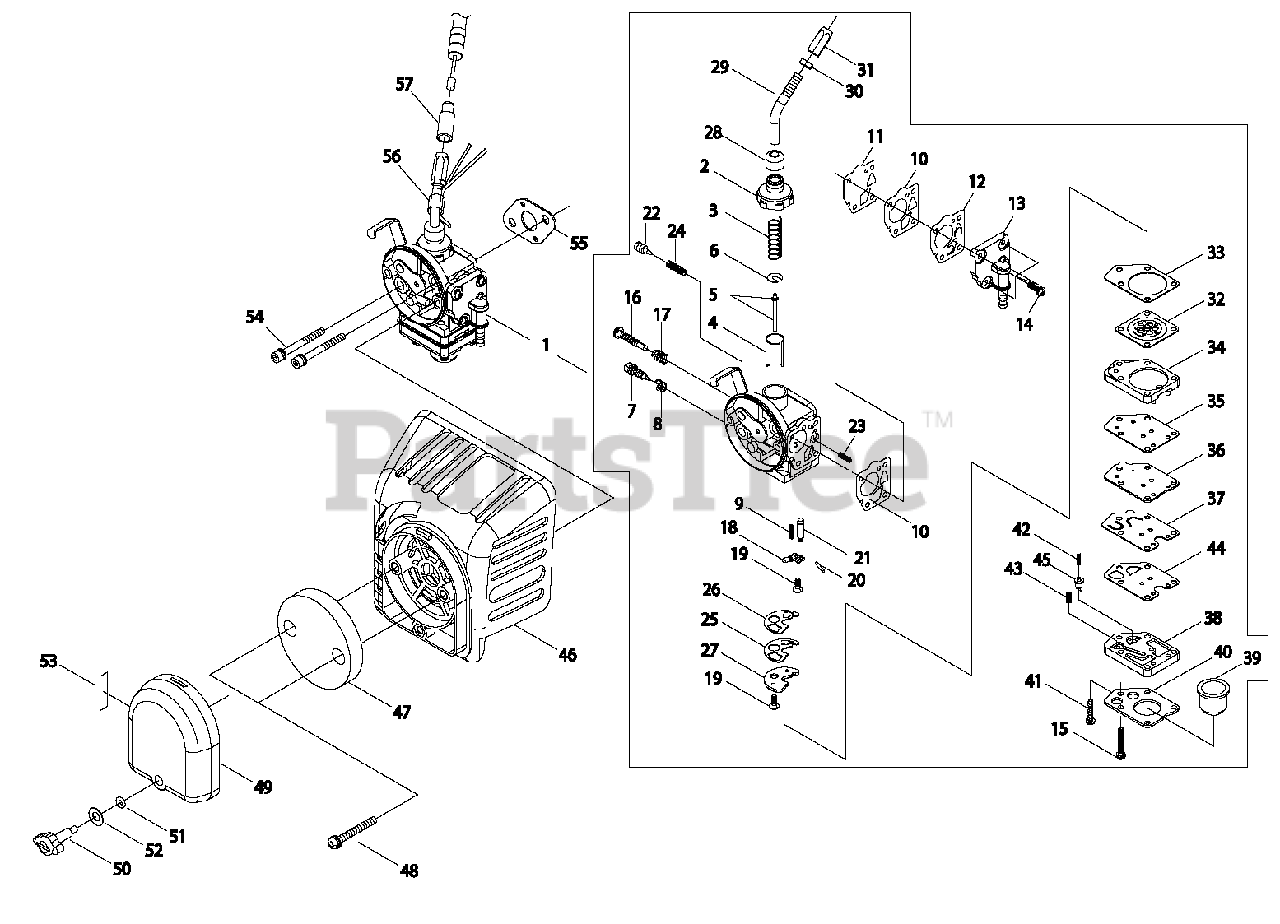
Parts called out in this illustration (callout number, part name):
1	CARBURETOR
2	CAP, CARBURETOR
3	SPRING, THROTTLE
4	VALVE, THROTTLE
5	NEEDLE, JET
6	SEAT, SPRING
7	NEEDLE - HIGH SPEED
8	SPRING, ADJUST
9	SPRING
10	GASKET, METERING
11	DIAPHRAGM, METERING
12	VALVE, PUMP
13	PUMP BODY ASSY
14	SCREW
15	SCREW - 3X20
16	SCREW, IDLE ADJUST
17	SPRING
18	LEVER, METERING
19	SCREW, METERING LEVER PIN
20	PIN, METERING LEVER
21	VALVE, INLET NEEDLE
22	SCREW, SLOW AIR
23	SPRING
24	SPRING
25	VALVE, CHECK
26	GASKET
27	PLATE
28	GROMMET
29	GUIDE, CABLE
30	LOCKNUT
31	NUT, CABLE ADJUST
32	DIAPHRAGM, METERING
33	GASKET, METERING
34	BASE, PURGE
35	GASKET
36	PLATE, PUMP
37	DIAPHRAGM
38	BASE, PURGE
39	BULB, PURGE
40	PLATE
41	SCREW
42	SPRING, RETURN
43	SPRING
44	GASKET
45	VALVE
46	CASE, AIR FILTER
47	FILTER, AIR
48	SCREW - 5X25
49	COVER, AIR FILTER
50	THUMBSCREW
51	O-RING
52	WASHER - CONICAL
53	LABEL - CHOKE
54	SCREW
55	GASKET, INTAKE
56	SLEEVE
57	CONNECTOR TUBE
